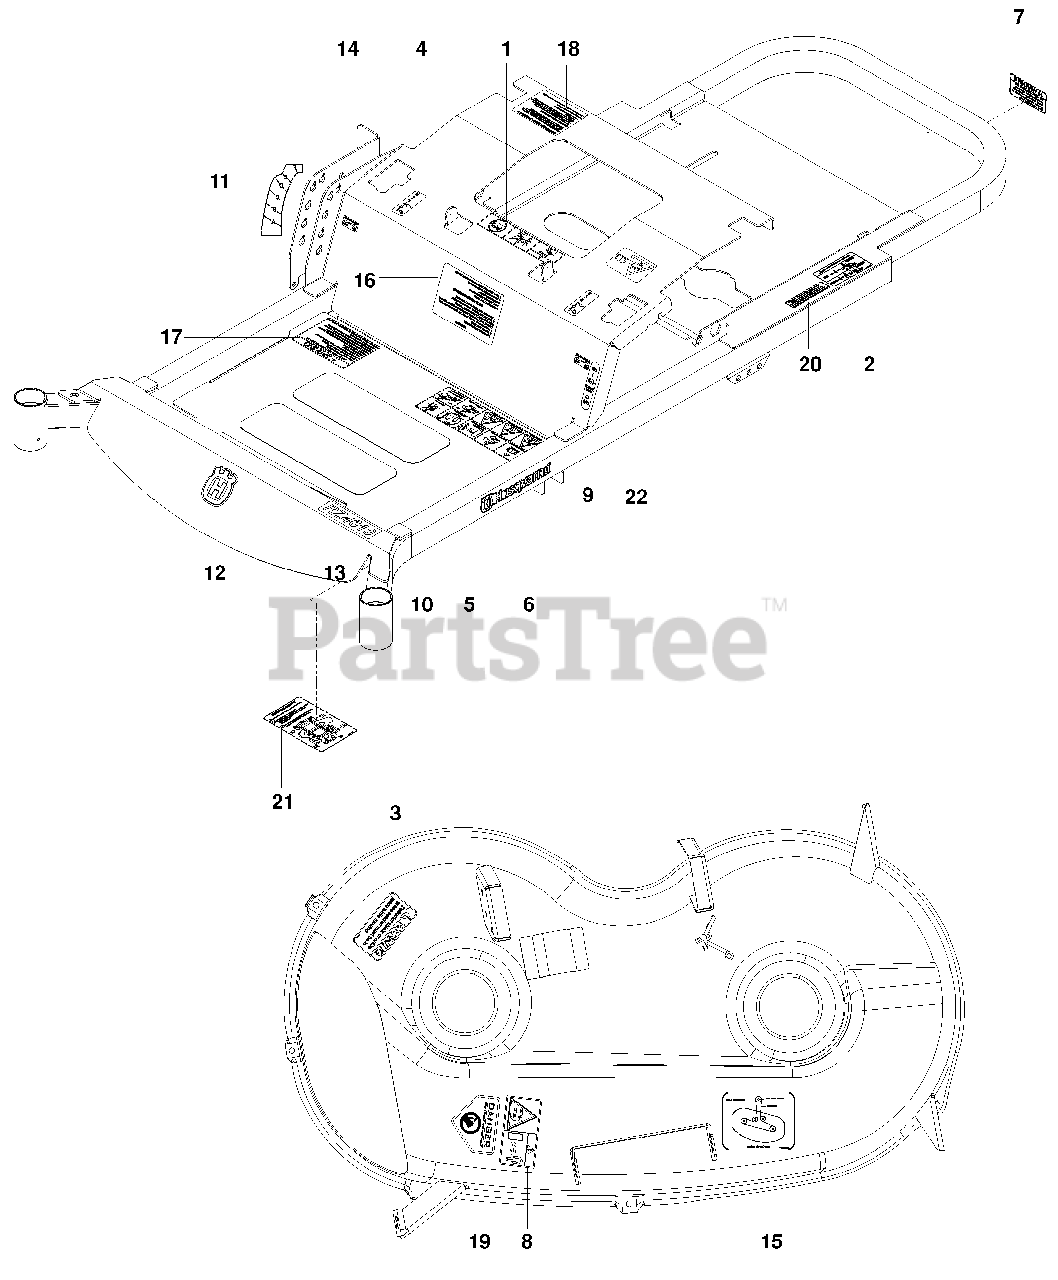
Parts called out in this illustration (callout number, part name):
1	DECAL, BATTERY WARNING
2	DECAL, DO NOT TOW
3	DECAL, DISCHARGE
4	DECAL, MOTION CONTROL
5	DECAL, WARNING
6	DECAL, HUSQVARNA
7	DECAL, EXHAUST
8	DECAL, SEVERING
9	DECAL, PARK BRAKE
10	ABRASIVE PAD
11	DECAL, HEIGHT
12	DECAL, CROWN
13	DECAL, RZ4619
14	DECAL, FST
15	DECAL, BELT ROUTING
16	DECAL, START
17	DECAL. SAFETY
18	DECAL, RESPONSIBILITIES
19	DECAL, BLADES
20	DECAL, SPARK ARREST
21	DECAL, SERVICE
22	DECAL, EXIT
